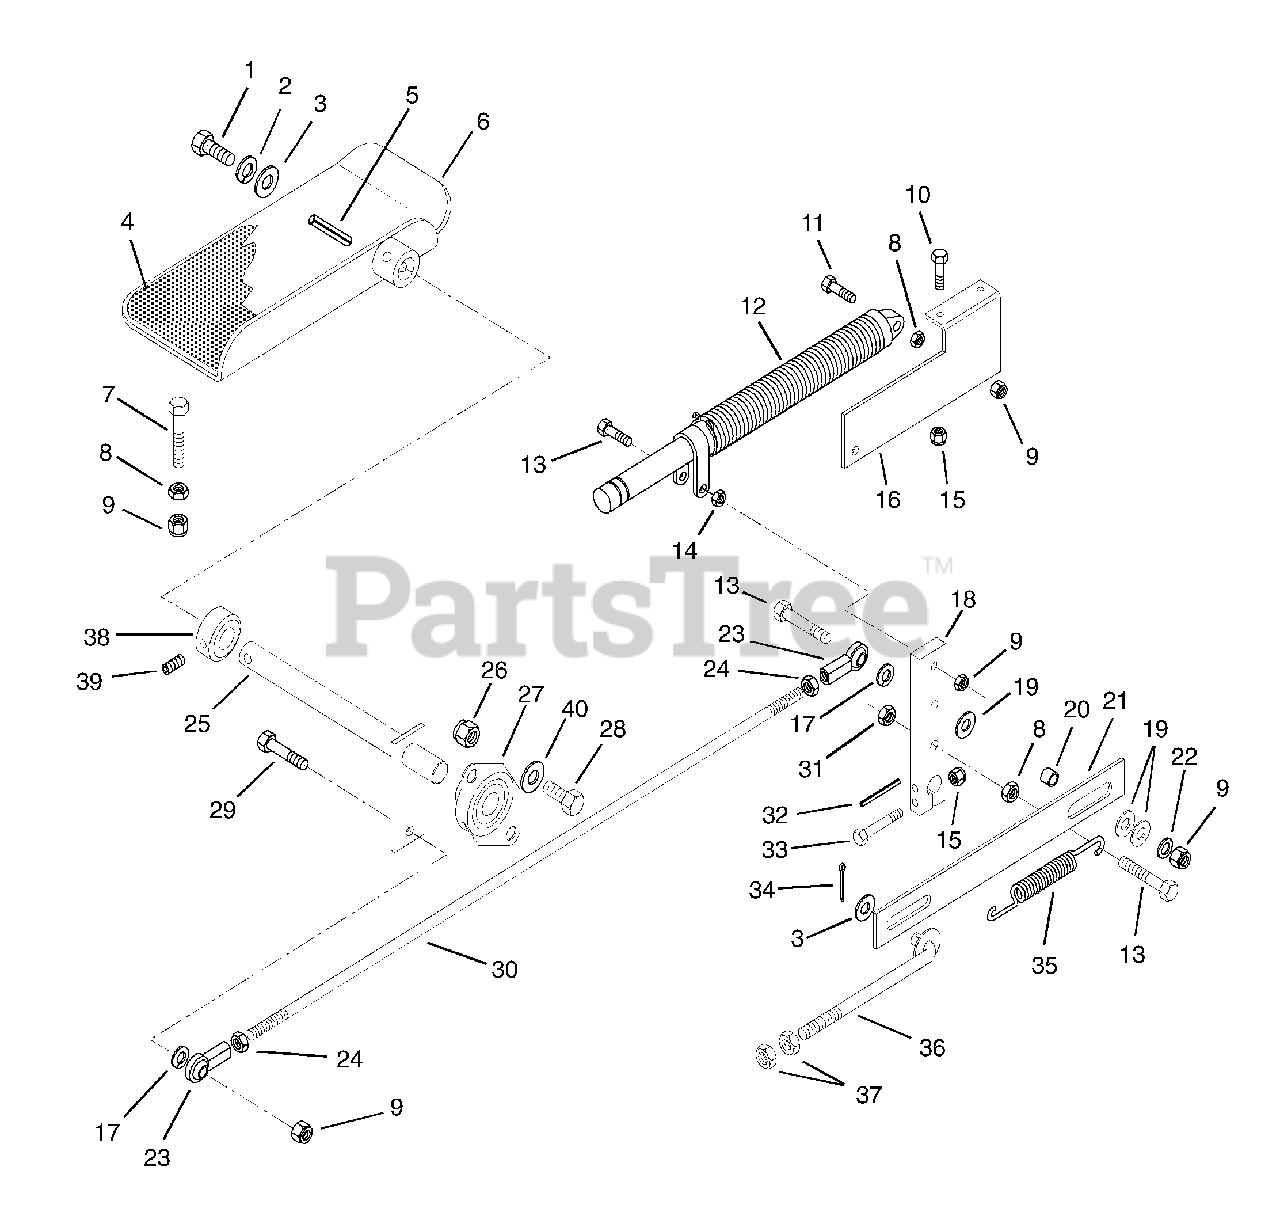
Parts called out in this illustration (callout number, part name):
1	Bolt-Hex .38-16 x 1.00 Grade 5
2	Washer-Lock .38 x .094
3	Washer-Flat-Steel .406 x .812 x .065
4	Cover, Large Foot-board
5	Pin-Roll .188 x 1.25
6	Weldment, Foot Control Lever
7	Bolt-Hex .31-18 x 2.50 Grade 5
8	Nut-Hex .31-18
9	Nut-Locking-Nylon .312-18
10	Bolt-Hex .25-20 x .50 Grade 5
11	Bolt-Hex .31-18 x 1.75 Grade 5
12	Damper
13	Bolt-Hex .31-18 x 2.00 Grade 5
14	Nut-Jam .312-18
15	Nut-Locking-Center .25-20
16	Bracket, Damper
17	Washer-Locking .31 x .078 Regular
18	Arm, Pump
19	Washer-Flat-Steel .531 x 1.06 x .095
20	Bushing-Flange .312 x .500 x .344 x .880
21	Strap, Neutral Detent
22	Washer-Flat-Steel .344 x .688 x .065
23	Rod End, 5/16" Female
24	Nut-Jam .375-24
25	Weldment, Control
26	Nut-Locking-Center .31-18
27	Bearing-Flange .751 x 2 Holes x .81
28	Bolt-Hex .31-18 x .75 Grade 5
29	Bolt-Hex .31-18 x 1.25 Grade 5
30	Rod, Speed Control
31	Nut-Locking-Center .31-18
32	Pin-Roll .250 x 1.000
33	Bolt-Hex .25-20 x 1.75 Grade 5
34	Pin-Cotter .09 x .75
35	Spring-Tension .091 x .500 x 5.50
36	Weldment, Detent Rod
37	Nut - Jam .38-24
38	Bearing Flange Locking Collar .75 x 1.85
39	Set Screw-Socket Head Cup Point .25-20 x .38
40	Washer-Flat-Steel .344 x .688 x .065
